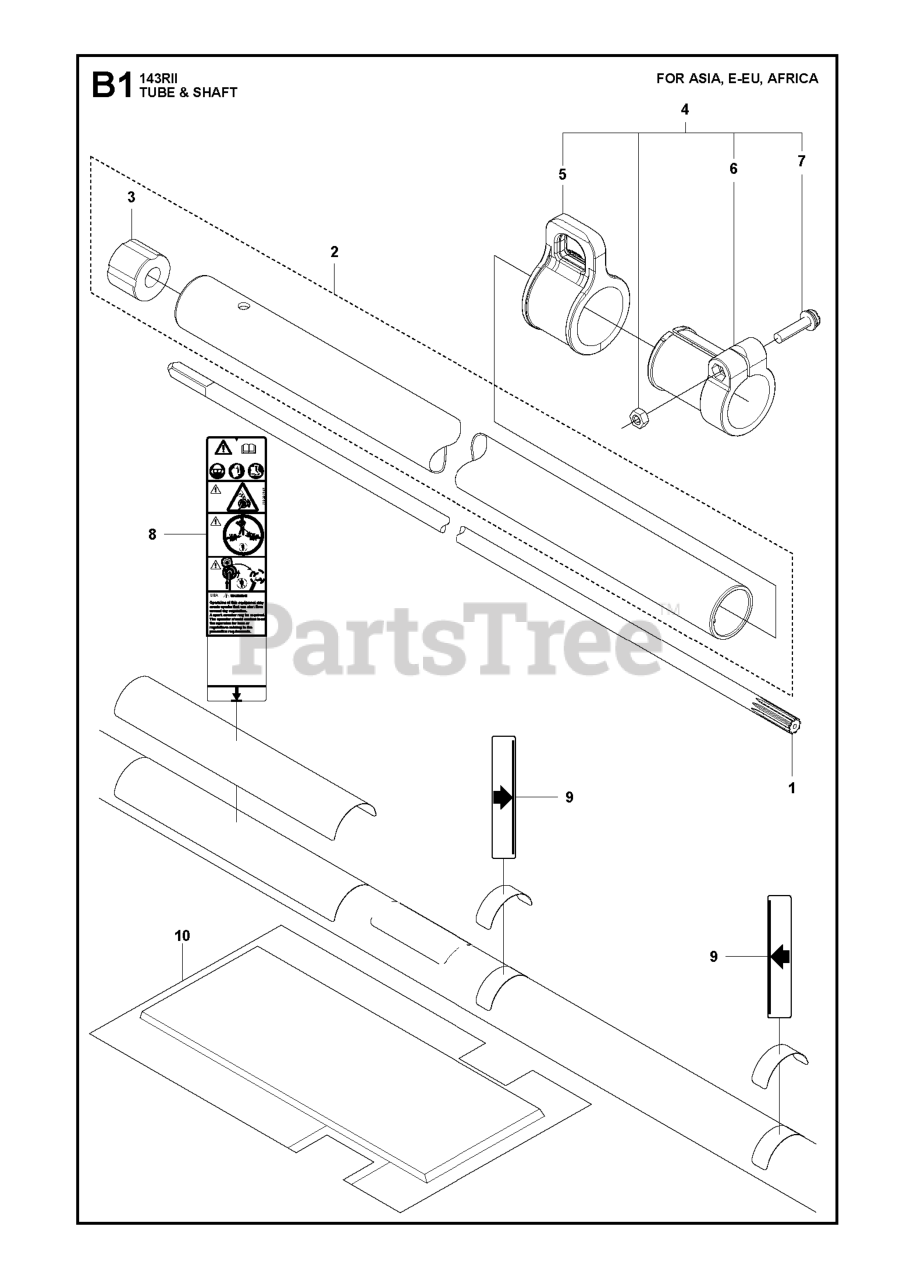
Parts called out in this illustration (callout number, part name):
1	DRIVE SHAFT
2	PIPE COMP.
8	LABEL WARNING TRIMMERS AND BRU
9	LABEL
10	PROTECTOR (RPLS 405017110)
